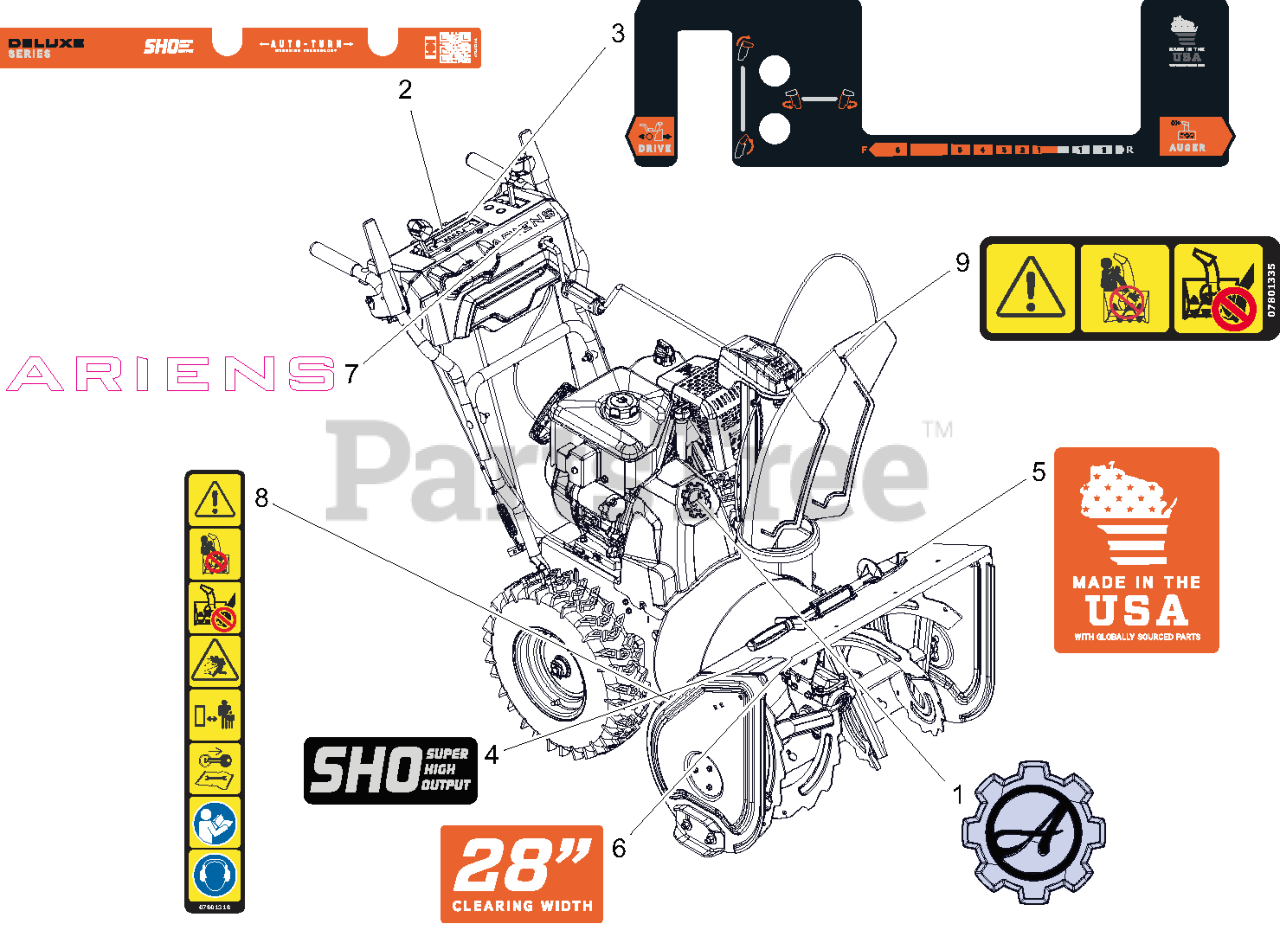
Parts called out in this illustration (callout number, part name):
1	DECAL, ARIENS - GEAR BADGE
2	DECAL- DASH - DELUXE SHO
3	DASH- CONTROL - SMALL DASH
4	DECAL, SHO
5	DECAL- MADE IN USA
6	DECAL- CLEARING - 28
7	DECAL- ARIENS - 7.46"
8	DECAL- SAFETY - DANGER
9	DECAL- DANGER
